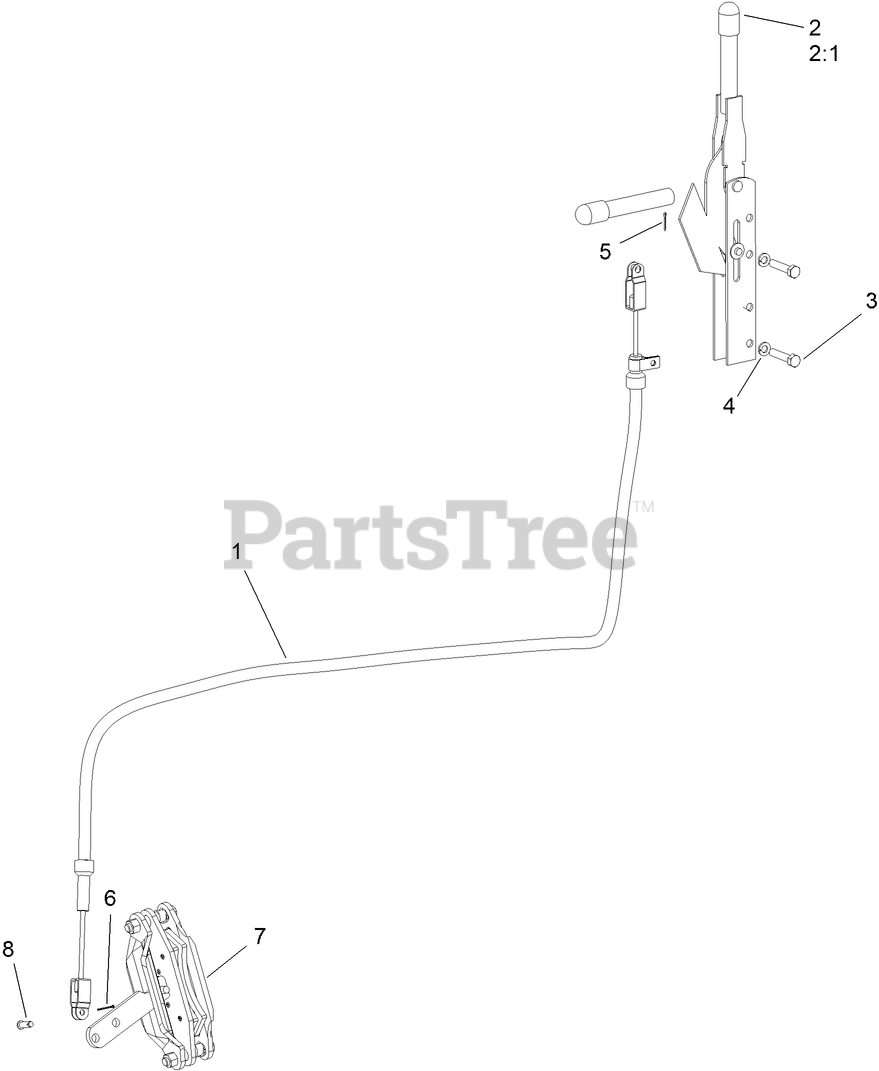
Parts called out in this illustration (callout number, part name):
1	CABLE-BRAKE
2	LEVER-BRAKE
2:1	SPACER
3	SCREW-HH
4	WASHER-LOCK
5	PIN-COTTER
6	PIN-COTTER
7	CALIPER ASM
8	PIN-CLEVIS
